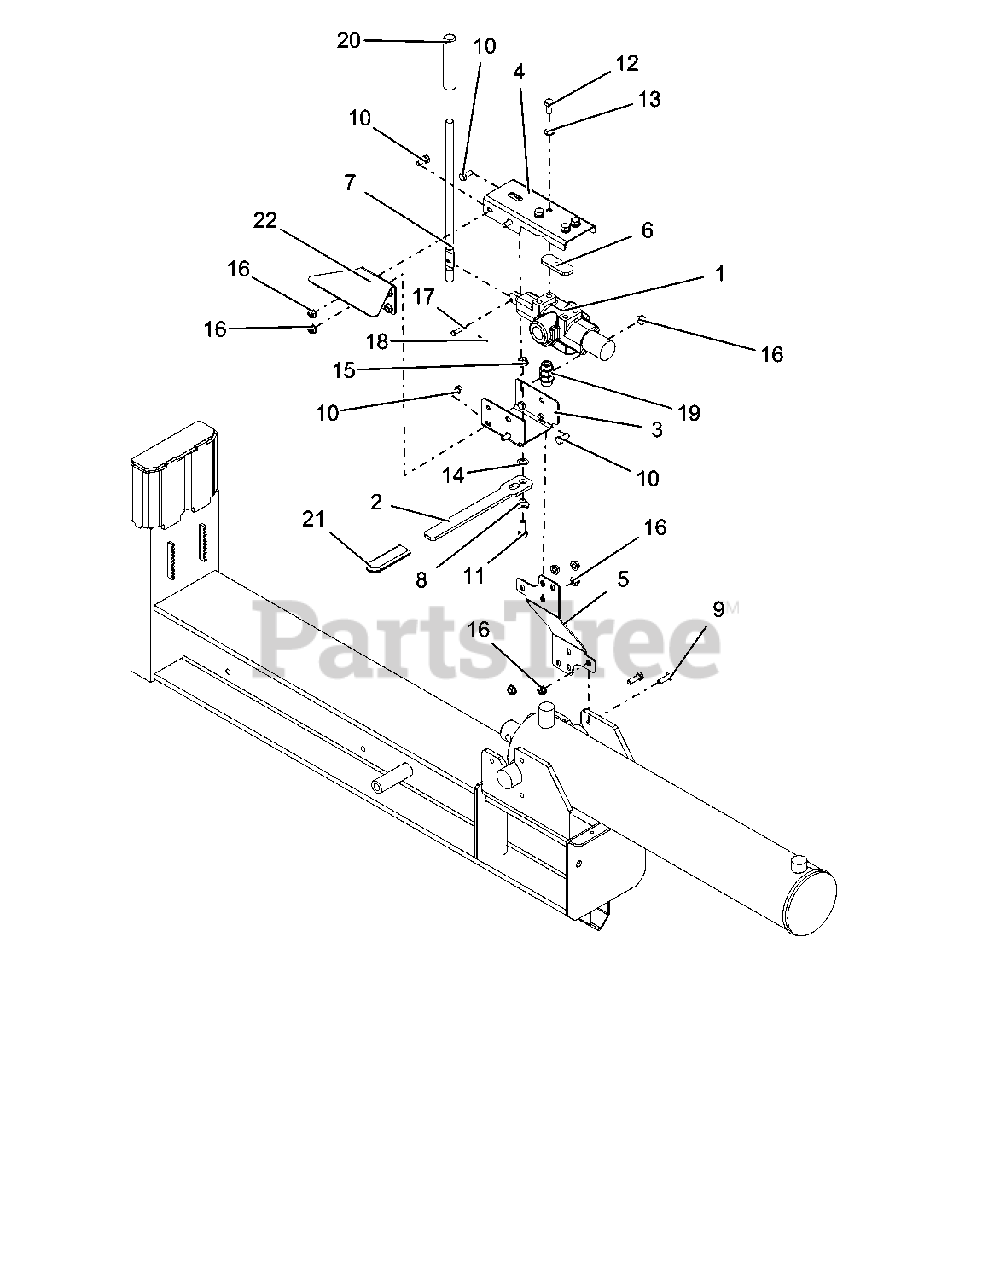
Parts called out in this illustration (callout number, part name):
1	VALVE, CONTROL -CE SPLITTER
2	HANDLE, SIDE 2 HAND CONTROL
3	BRKT, LOWER 2 HAND CONTROL
4	BRKT, UPPER 2 HAND CONTROL
5	BRACE, SIDE 2 HAND CONTROL
6	SPCR, BRKT 2 HAND CONTROL
7	HANDLE, UPPER 2 HAND CONTROL
8	BSHG, FLG .385 X .500 X .875 X .406
9	BLT-HEX .31-18X1.00 GR5 YWZC
10	BLT-HEX .31-18X.75 GR5 YWZC
11	BLT-HEX .38-16X1.00 GR5 YWZC
12	BLT-HEX .38-16X.75 GR5 YWZC
13	WSHR-LK .38X.094 REG YWZC
14	WSHR-FL-STL .520X.810X.033 YWZC
15	NUT, LK-TOP-FLG .38-16 YWZC
16	NUT, LK-TOP-FLG .312-18 YWZC
17	PIN, CLEV .250x1.125
18	@PIN-CTR .06X.75 EXTPRSQCT YZ
19	FTG, HYD - STR 08MAORB-08MORB
20	GRIP, .475 ID X 4.25 LG
21	GRIP, HANDLE -FLAT .250 X 3.500
22	BRKT, SIDE 2 HAND CONTROL
